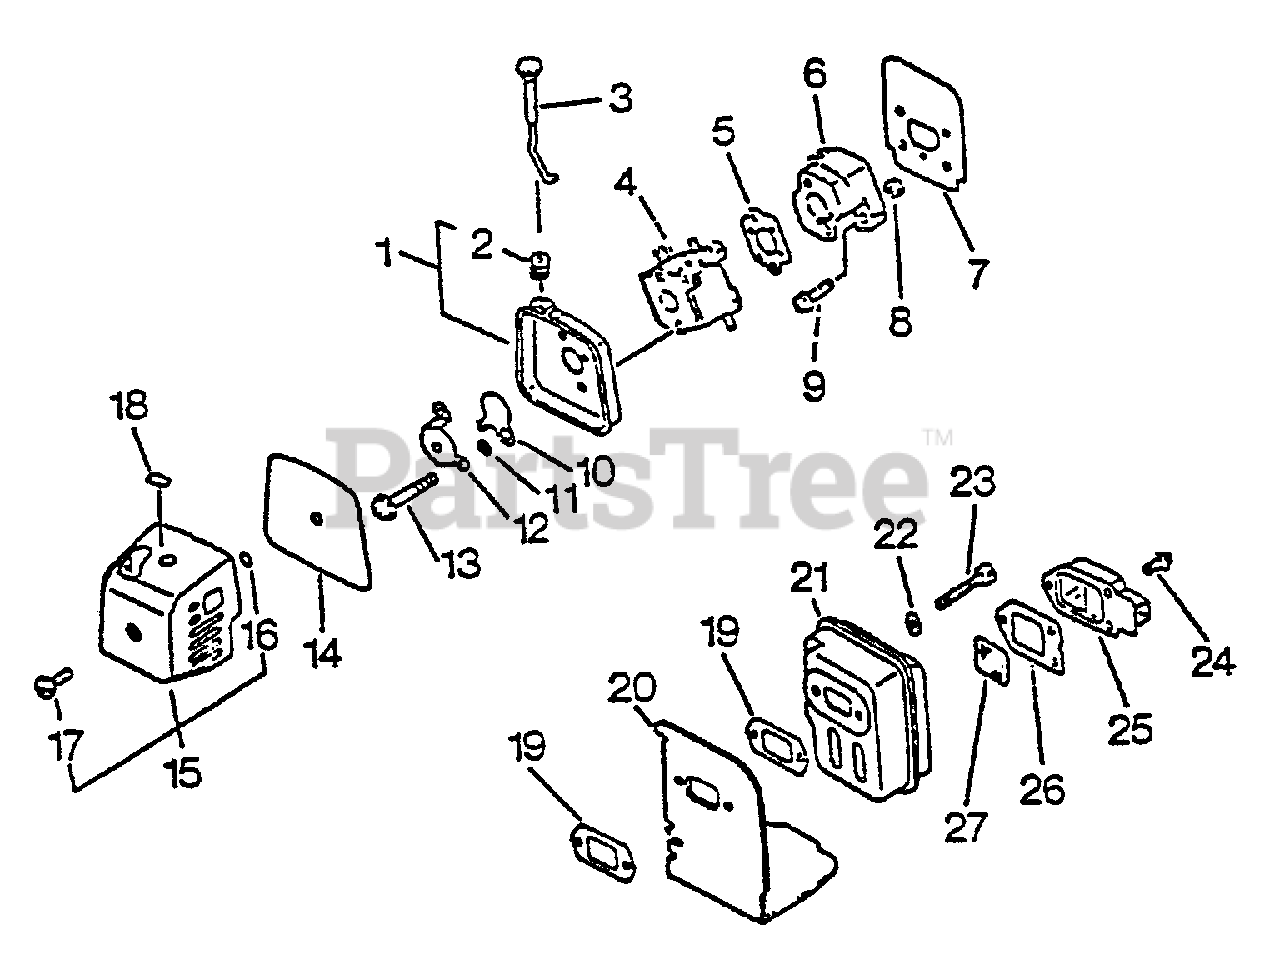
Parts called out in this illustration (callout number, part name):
1	CASE, AIR FILTER
2	GROMMET, CHOKE
3	ROD, CHOKE
4	CARBURETOR
5	GASKET, INTAKE
6	INSULATOR, INTAKE
7	HEAT SHIELD, INTAKE
8	NUT M5
9	SCREW 5×20
10	SHUTTER, CHOKE
11	WASHER 5.2×8×0.8T
12	CASE, AIR FILTER
13	SCREW 5×57
14	FILTER, AIR
15	COVER ASSY, AIR FILTER
18	LABEL, CHOKE
19	GASKET, EXHAUST
20	COVER, EXHAUST
21	MUFFLER ASSY
22	WASHER, FLAT 5.5×10×0.8
23	BOLT 5×55
24	SCREW 4×10
25	GUIDE, EXHAUST - INNER
26	GASKET, EXHAUST
27	SCREEN, SPARK ARRESTER
